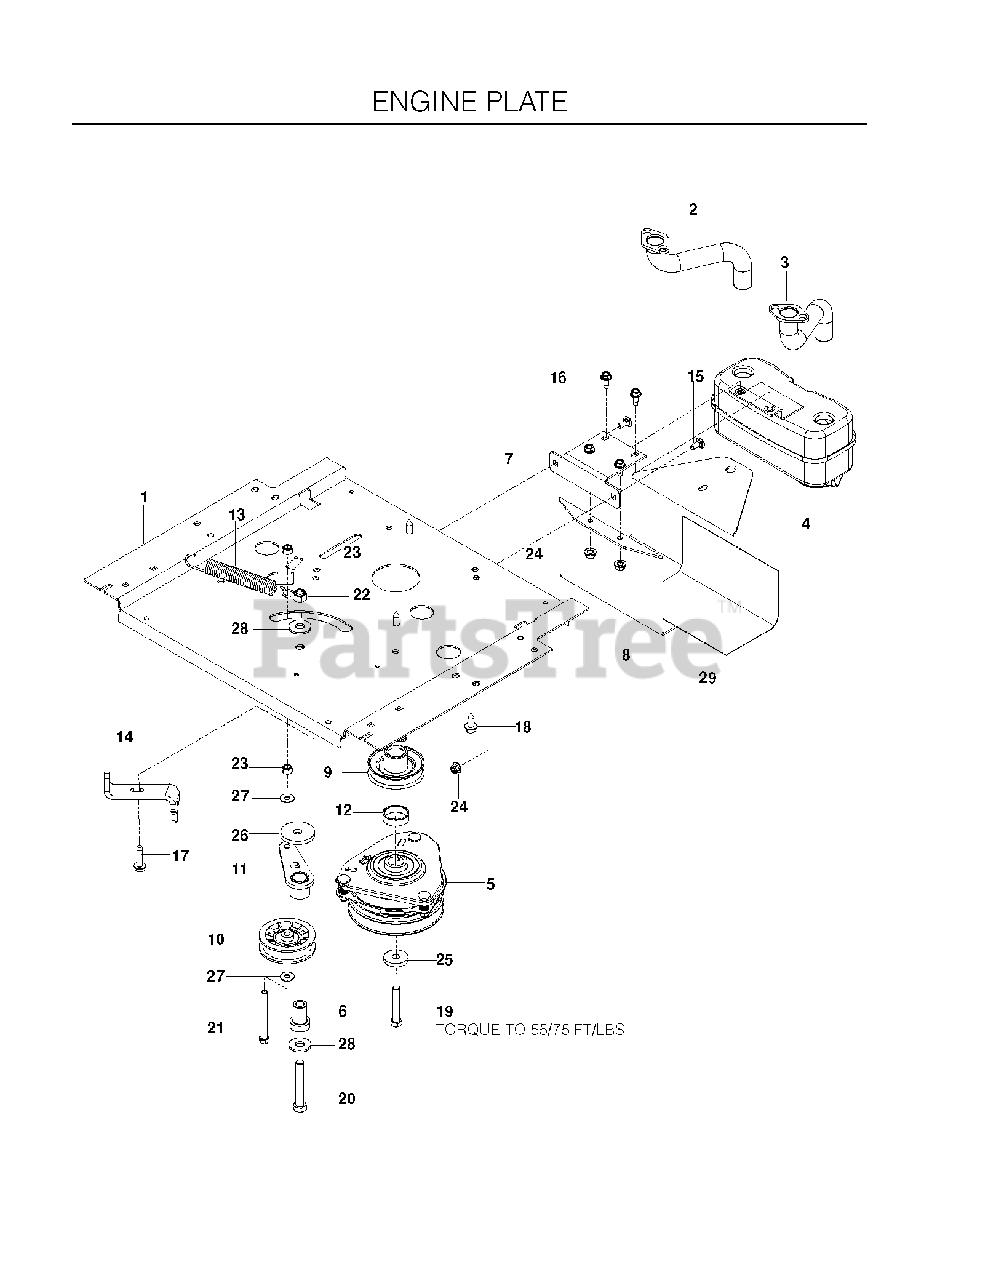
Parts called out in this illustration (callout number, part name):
1	PLATE, ENGINE WIDE, BLACK
2	RP.EXHAUST.TUBE.LH.BS/TWIN
3	EXHAUST.TUBE.RH.BS/TWIN
4	MUFFLER ASM TWIN
5	IDLER SPINDLE
6	HEAVY WASHER
7	HCS 1/2C X 3 1/4
8	WASH USS FLAT 1/2
9	RP NUT 1/2-13 HEX NYLOC ZD
10	BRACKET, MUFFLER, BLACK
11	GUARD, MUFFLER, BLACK
12	RP PULLEY, ENGINE
13	HCS 3/8-16X3 1/2 GR5
14	WASHER 5/16 FLAT
15	NUT 3/8-16 NYLOC
16	BOLT 5/16-18 X 3/4
17	BOLT 5/16C X 3/4" CARRIAGE
18	CLUTCH, WASHER
19	HHFS 3/8-16 X 1.0 THD FORMING
20	IDLER ARM WELDMENT
21	PULLEY, IDLER RAKE & ZTR
22	BOLT 3/8-16 X 1 1/2 ZINC CLEAR
23	SPRING, DECK DRIVE
24	5/16-18 NYLOC FLANGE NUT
25	CLUTCH.ELECTRIC.LT.48"*
26	SPACER, HUB PULLEY
27	CLUTCH STOP BLK
28	HCS 7/16-20 X 2.5 GR8
29	HEAT SHIELD
